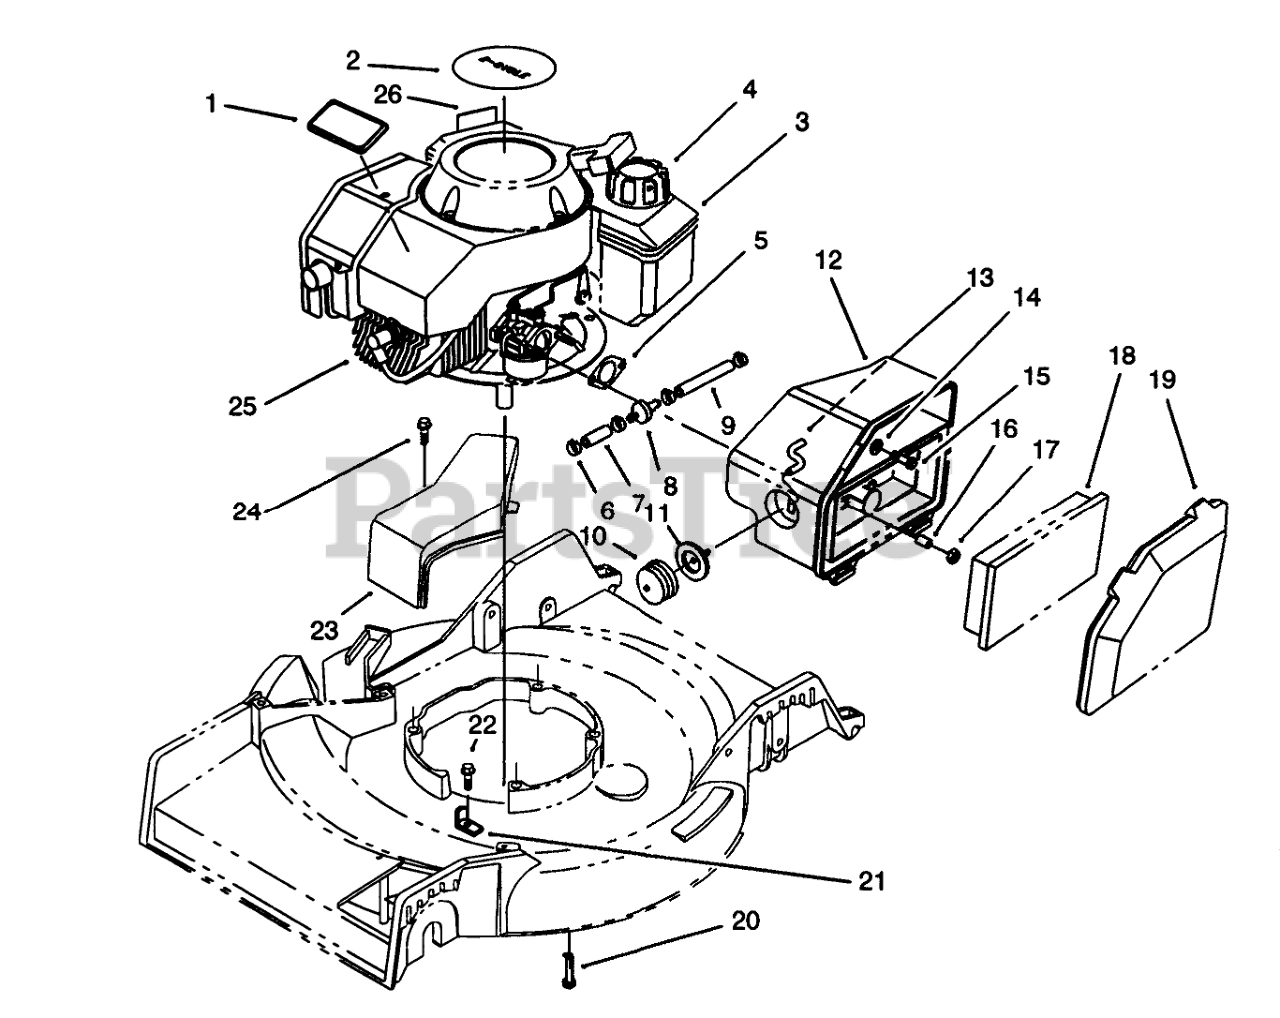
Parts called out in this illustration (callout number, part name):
1	TORO LOGO PLT
2	DECAL- 2 CYC RECOIL
3	FUEL TANK ASM
4	GAS CAP ASM
5	GASKET-AIR CLEANER
6	CLAMP-FUEL LINE
7	HOSE-FUEL
8	FILTER-FUEL
9	HOSE-FUEL
10	BULB-PRIMER
11	BODY-PRIMER
12	BODY-AIR CLEANER
13	HOSE-PRIMER
14	WASHER-FLAT
15	SCREW-HH
16	SPACER
18	ELEMENT-AIR CLEANER
19	COVER-AIR CLEANER
20	SCREW-HHF, WHIZ
21	BELT GUIDE
22	SCREW-HWHTF
23	BELT COVER 21" S D
24	SCREW-HWH
25	Engine
26	Decal-Maintenance
